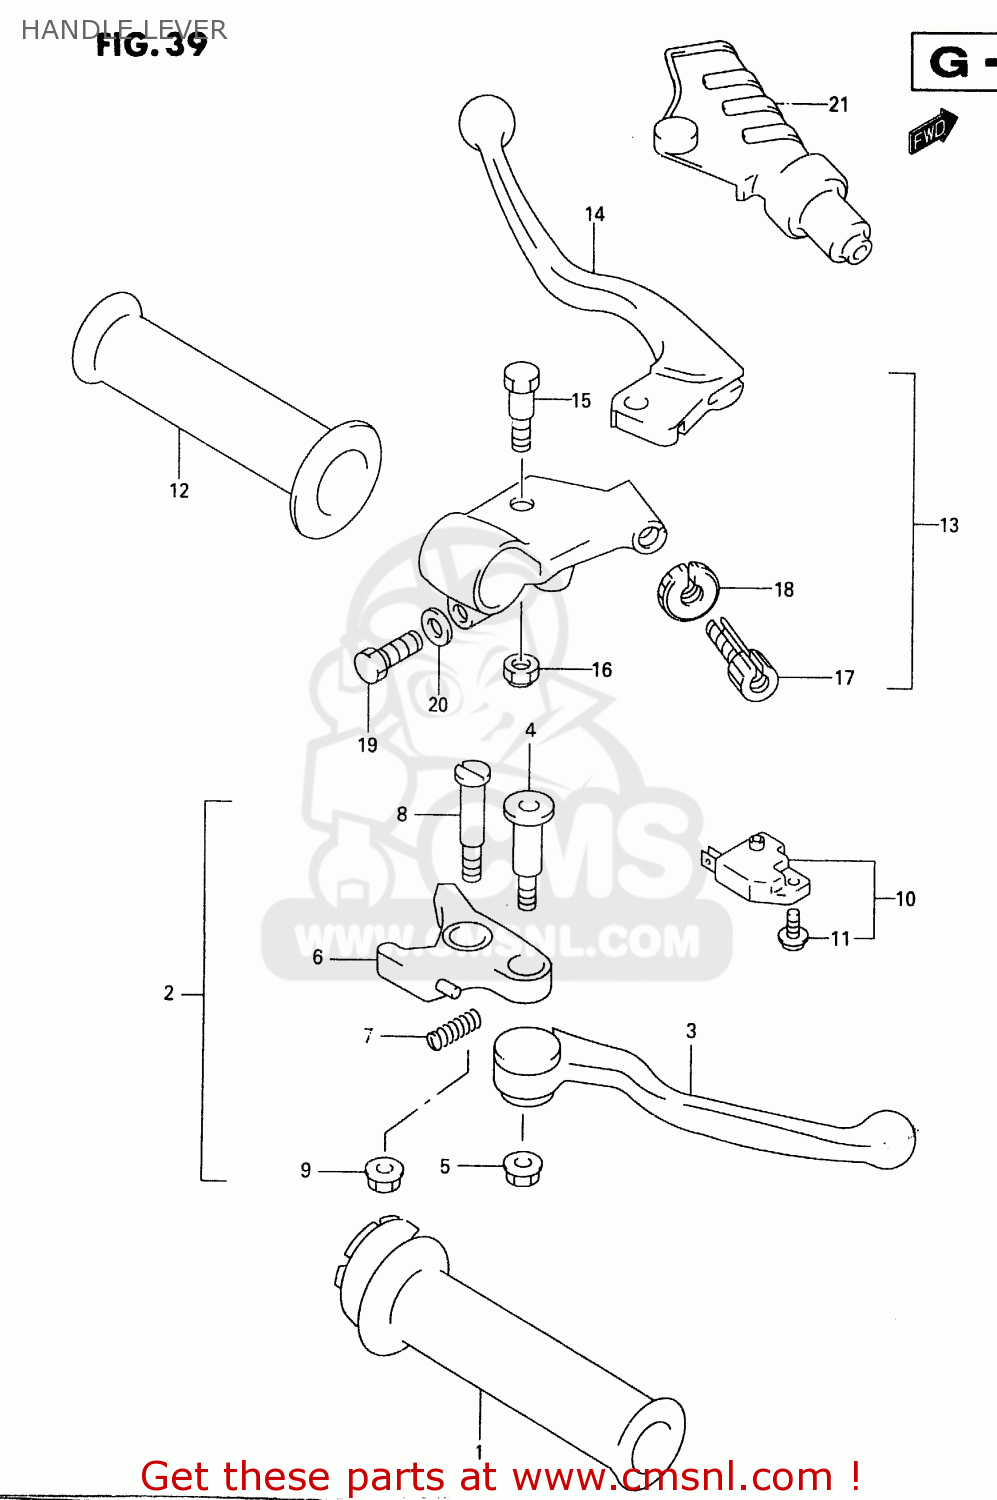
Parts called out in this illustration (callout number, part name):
1	GRIP,THROTTLE
2	LEVER ASSY,BRAKE
3	LEVER,ADJUST
4	BOLT,LEVER
5	NUT
6	KNOCKER
7	SPRING
8	BOLT,LEVER PIVOT
9	NUT
10	SWITCH ASSEMBLY,STOP
11	SCREW
12	GRIP,LEFT
13	LEVER ASSY,CLUTCH
14	LEVER,CLUTCH
15	BOLT,LEVER SET
16	NUT
17	ADJUSTER,CABLE
18	NUT,CABLE ADJUSTER
19	BOLT
20	WASHER
21	COVER,CLUTCH LEVER
